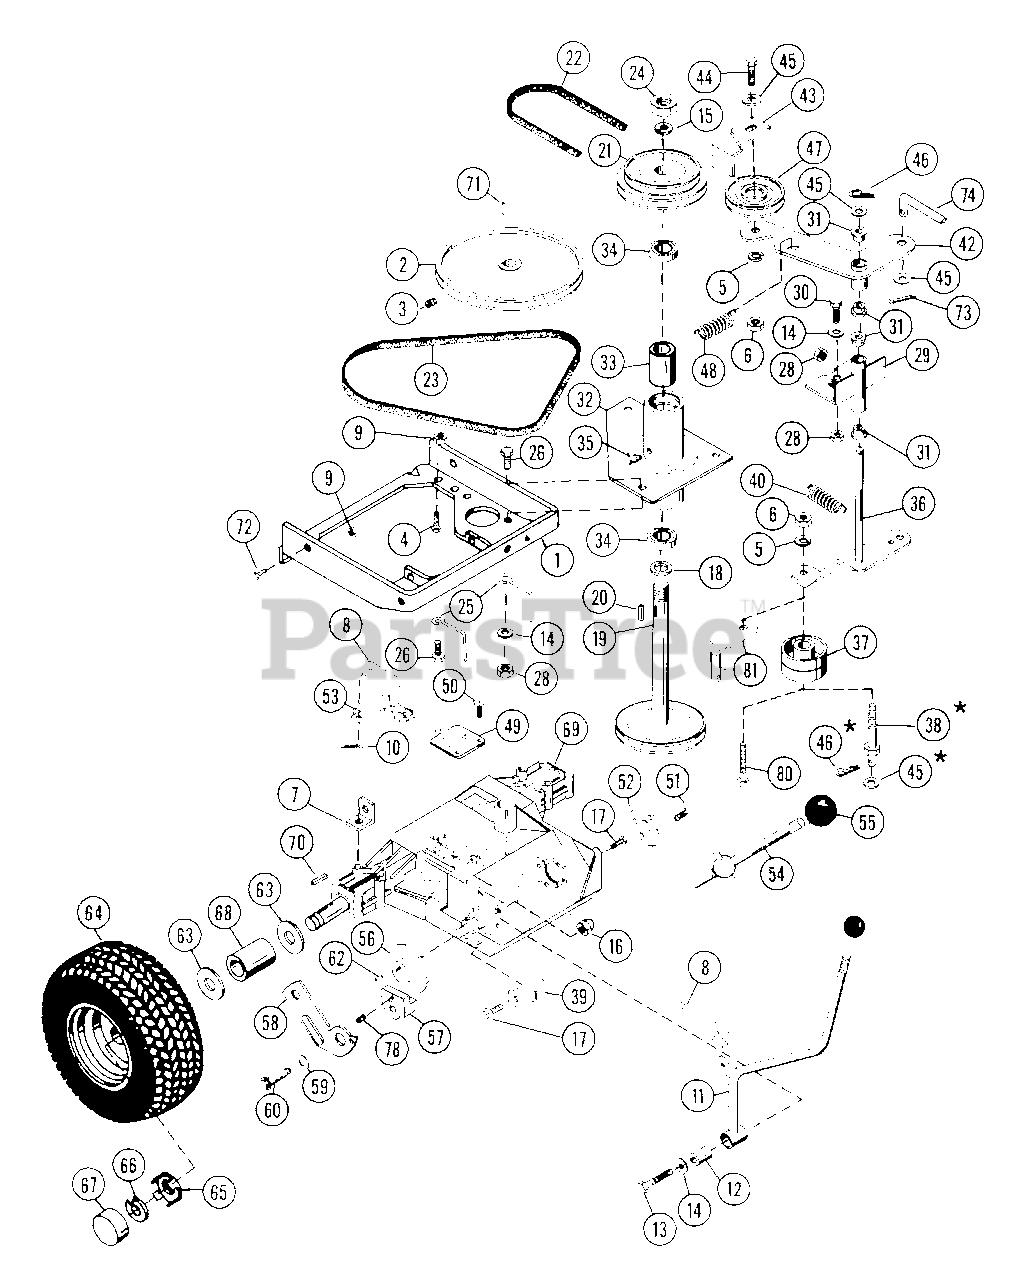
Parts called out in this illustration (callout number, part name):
1	TRANSAXLE MOUNT
2	PLY-V 6.00 X .63 W/KEY (ADAMS)
3	SCR-SET .25-20X.25 SKHCUPNY OH
3	BLT-HEX .38-16X2.75 PL GR5
5	WSHR-LK .375X.115 HVY PL
6	NUT-HEX .375-16
8	SELECTOR ROD
9	NUT-LK TOP .375-16 GR C YWZC
10	PIN-COTR .09X.75 PL
11	RANGE SELECTOR LEVER
12	SPACER .50 X .32 X 1.00
13	BLT-HEX .25-20X2.00 PL GR5
14	WSHR-FL-STL.312X.734X.065PL
15	WSHR-LK-INT .750X.050 MED
16	NUT-LK TOP .250-20 PL
17	BLT-HEX .25-20X1.00 PL GR5
18	WSHR-FL-STL .755X1.250X.125
19	JACKSHAFT SPINDLE
20	KEY-SQ .188X1.0X.188 SAE 8630
21	TRIPLE GROOVE PULLEY
22	V-BELT, 4L-RAW EDGE
23	V-BELT, 4L-RAW EDGE
24	NUT-JAM .75-10 PL
25	BELT FINGER
26	BLT-HEX .31-18X1.00 PL GR5
27	WSHR-LK .375X.115 HVY PL
28	NUT-LK-TOP .312-18 GR C PL
29	IDLER PIVOT
30	BLT-HEX .31-18X.75 PL GR5
31	BSHG-FLG .372X.500X.312X.625NY
32	SPINDLE HOUSING
33	BEARING SPACER .770X1.00X3.268
34	BRG-BALL .750X1.781X.61
35	HYDRAULIC LUBRICATION FITTING
36	IDLER ARM
37	IDLER-FLAT 2.25 X .38
38	IDLER MTG BOLT
39	SPRING ANCHOR
40	SG-TENS .091X.73X5.28 WLD 30
42	IDLER ARM
43	BELT RETAINER
44	BLT-HEX .38-16X1.75 PL GR2
45	WSHR-FL-STL.406X.812X.065PL
46	PIN-HAIR INT .08X.18X1.18
47	IDLER-V 3.06 X .38
48	SG-TENS .105X.812X3.88 WLD 15
49	HI-LO COVER PLATE
50	SCR-MCH 8-32X.50 SLTR PL
51	SCR-MCH 10-24X.50 SLTR PL
52	NYLON COVER
53	HI-LO SHIFT LEVER
54	SHIFT LEVER ASSY
55	SHIFT BALL
56	BRAKE DISC
57	BRAKE JAW ASSY
58	ACTUATING LEVER ASSY
59	WSHR-FL-STL .505X.750X.006
60	SHOULDER BOLT
61	FRICTION PAD
62	KEY-WDRF .188X.625X.25 SAE 61
63	WSHR-FL-STL .755X1.375X.062 PL
64	WHEEL & TIRE ASSEMBLY
65	SPINDLE CUP
66	RG-RTNG-EXT .750X.050
67	HUB CAP
68	SPACER 1.000 X .760 X 1.562
69	TRANSAXLE ASSEMBLY
70	KEY-SQ .188X2.0X.188 SAE 8630
71	KEY-WDRF .188X.75X.313 SAE 9
72	BLT-HEX .38-16X1.00 PL GR5
73	PIN-COTR .12X1.0 PL
74	CLUTCH ROD
77	WSHR-FL-STL .38X.875X.083 PL
78	SCR-SET 8-32 FOOTE 1606
80	BLT-HEX .38-16X1.75 PL GR2
81	BRACKET
